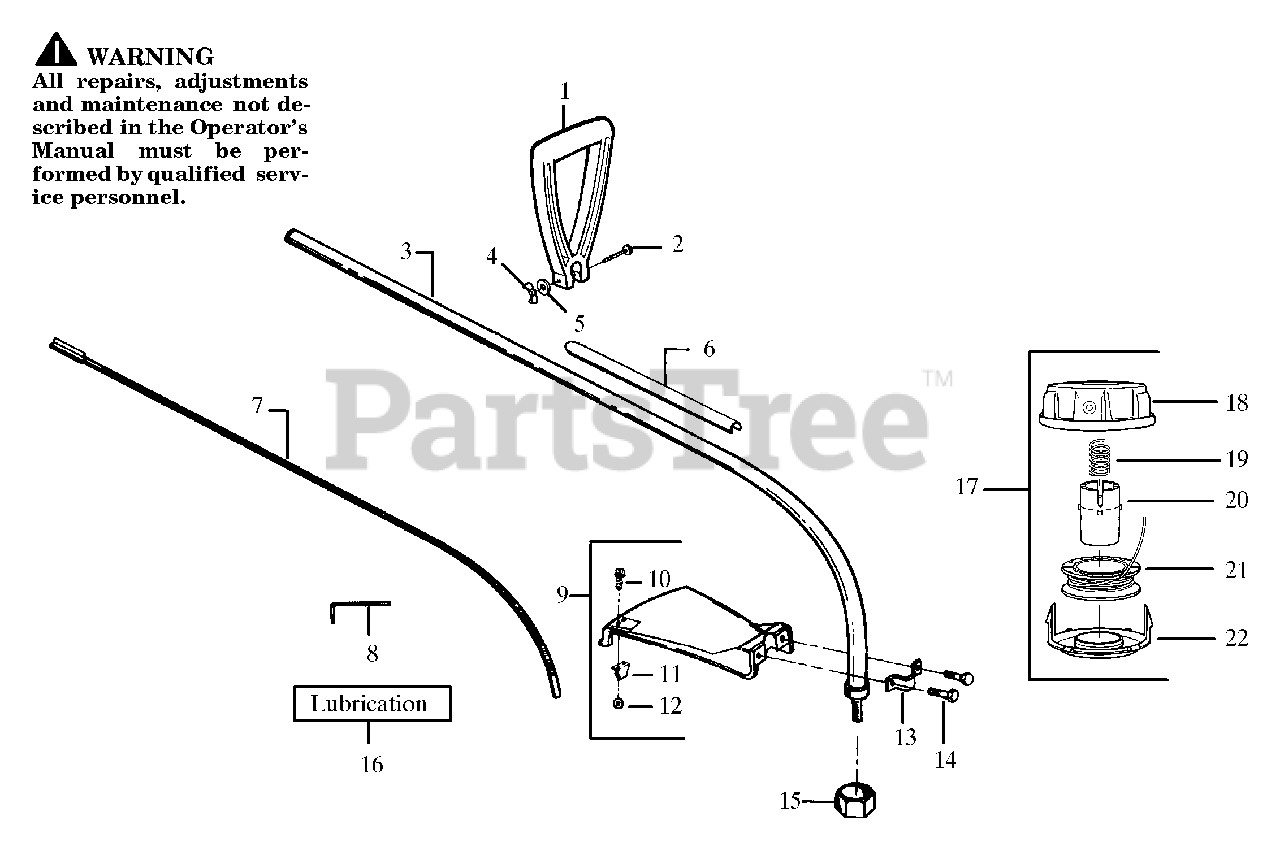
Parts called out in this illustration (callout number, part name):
1	"D" Handle
3	Drive Shaft Housing Models HP22 & HP30T
3	Drive Shaft Housing Models HP22T
6	Shaft Warning Decal
7	Drive Shaft
8	Hex Wrench (5/32)
9	Shield Kit Ass'y.
11	Line Limiter
12	Locknut
13	Shield Bracket
14	Screw
15	Dust Cup
16	Shaft Lubrication
17	Cutting Head Ass'y.
18	Hub Ass'y.
20	Release Button
21	Spool w/Line
